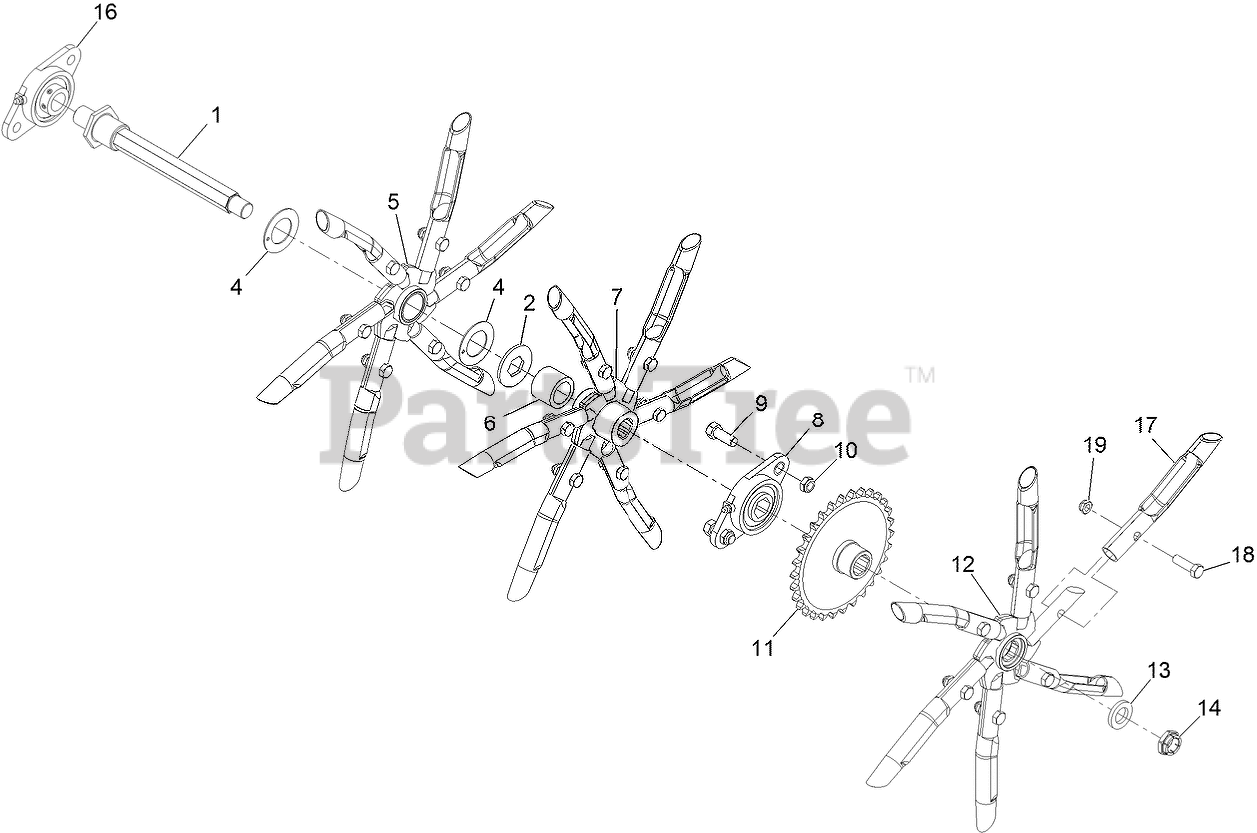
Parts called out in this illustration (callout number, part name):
1	TINE SHAFT ASM
2	KEEPER-TINE, FLOATING
4	WASHER-THRUST
5	FLOATING SPYDER ASM
6	SPACER-TINE
7	DRIVEN SPYDER ASM
8	BEARING-HEX BORE
9	SCREW-HH
10	NUT-LOCK
11	SPROCKET ASM
12	DRIVEN SPYDER ASM
13	WASHER-SPACER
14	NUT-LOCK
16	BEARING-ROUND BORE
17	TINE-CORING (3/4 INCH)
18	SCREW-HH
